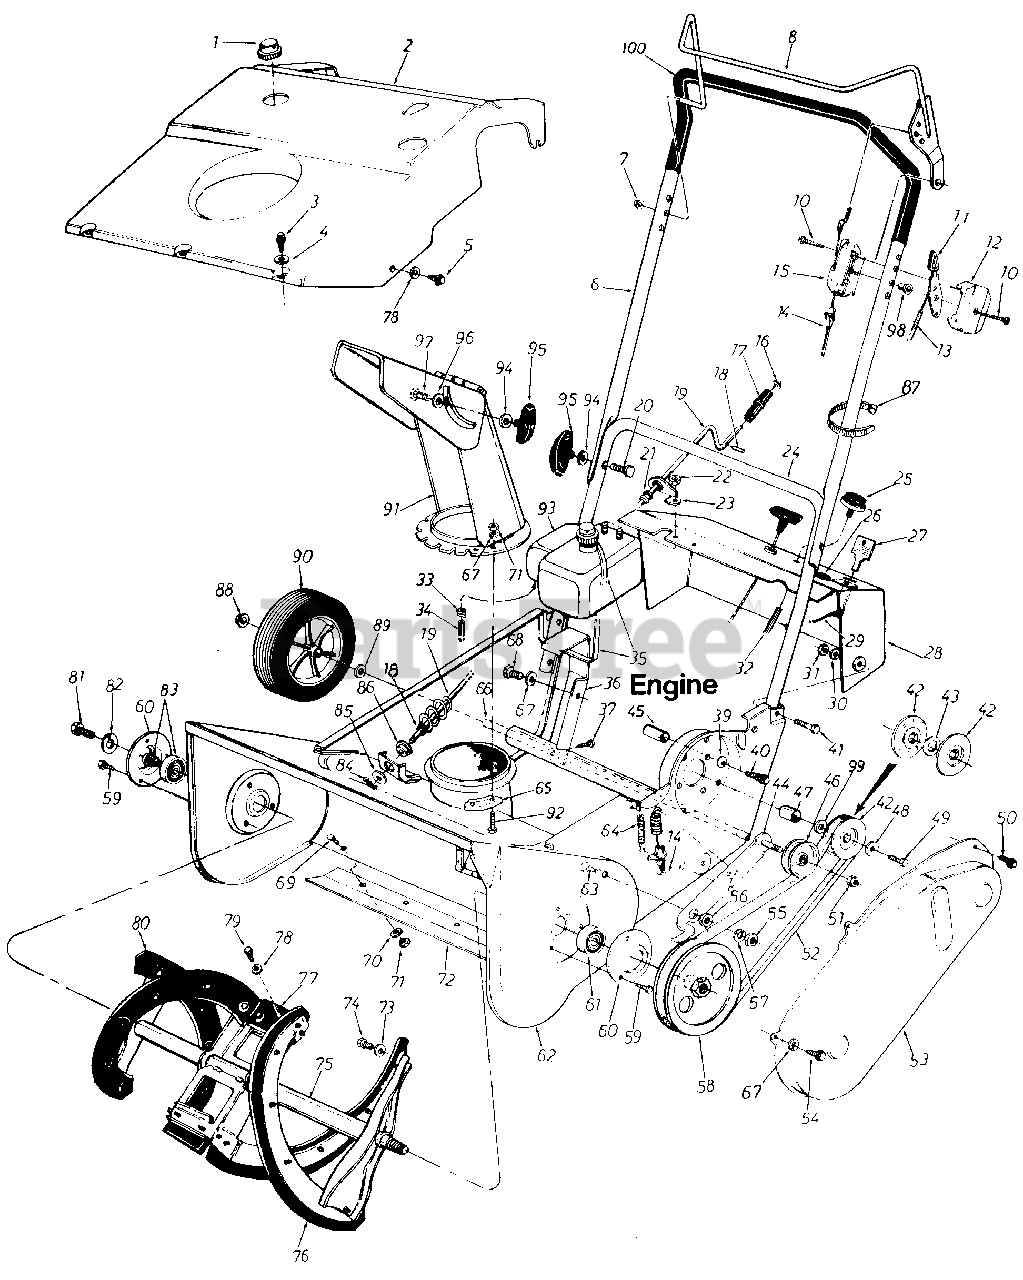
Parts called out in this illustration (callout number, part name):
1	Gas Tank Cap
2	21" Shroud
3	Hex B-Tap Scr. #10 x .38" Lg.
4	Spr.-Wash. .206" I.D. x .448" O.D.
5	Hex L-Wash. Hd. AB-Tap 1/4 x .62" Lg.
6	Upper Handle
7	Cap Speed Nut
8	Control Handle Ass'y. L.H.
10	Truss Mach. Hi-B Tap Scr. #12 x 1.5" Lg.
11	Throttle Lever
12	Control Panel Half
13	Throttle Wire 35"
14	Clutch Cable 35" Lg.
15	Clutch Panel Half
16	Push Cap 3/8" Rod
17	Knob 3/8" Dia. Hole
18	Roll Pin 1/8" Dia. x .63" Lg.
19	Chute Crank Ass'y.
20	Curved Carriage Bolt 5/16-18 x 1.75" Lg.
21	Chute Crank Grommet
22	Hex L-Nut 1/4-20 Thd.
23	Upper Chute Crank Brkt.
24	Lower Handle
25	Primer
26	Plastic Plug
27	Plastic Key
28	Dash Panel Ass'y.
29	Ignition Wire
30	L-Wash. 5/16" I.D.
31	Hex Nut 5/16-18 Thd.
32	Primer Hose 11" Lg.
33	Hose Clamp .406" Dia.
34	Gas Line 9" Lg.
35	Cable Tie 17.75" Lg.
36	Engine Support Brkt.
37	Hex L-Wash. Hd. AB-Tap Scr. 1/4 x.62" Lg.
39	Bell-Wash. .345" I.D. x .88" O.D.
40	Hex Bolt 5/16-18 x 1.5" Lg.
41	Hex Bolt 5/16-18 x 1.5" Lg.
42	3/8" "V"-Pulley Half .625" I.D. x 6.0 " O.D.
43	Fl.-Wash. .635" I.D. x .93" O.D.
44	Idler Brake Brkt. Ass'y.
45	Spacer .325" I.D. x .625" O.D. x .875"
46	Fl-Idler w/Flanges 2.12" O.D.
47	Spacer .635" I.D. x .89" O.D. x .57"
48	Bell-Wash. .345" I.D. x .88" O.D.
49	Hex Bolt 5/16-24 x .75" Lg.
50	Hex L-Wash. Hd. AB-Tap Scr. 1/4 x .62" Lg.
51	Hex Patch L-Nut 3/8-24 Thd.
52	"V"-Belt
54	Hex B-Tap Scr. 1/4" x .38" Lg.
55	Hex Nut 5/16-18 Thd.
56	Shld Spacer .50" Dia. x .27" Lg.
57	L-Wash. 5/16" I.D.
58	1/2" "V"-Pulley 1/2-20 LH. x 6" O.D.
59	Hex B-Tap Scr. 1/4" x .38" Lg.
62	21" Blower Hsg. Ass'y.
63	Truss Mach. Scr. 5/16-18 x .75" Lg.
64	Extension Spring .33" O.D. x 1.12" Lg.
65	Chute Flange Keeper
66	Wheel Axle Tubing
67	L-Wash. 1/4" I.D.
68	Hex Wash. S-Tap Scr. 1/4-20 x.50" Lg.
69	Carriage Bolt 1/4-20 x .62" Lg.
70	Fl.-Wash. .281" I.D. x .73 0. D.
71	Hex Nut 1/4-20 Thd.
72	Shave Plate
73	Fl-Wash. .281" I.D. x .50" O.D.
74	Hex Wash. B-Tap Scr. 1/4 x .62"
75	Auger Ass'y. 21
76	Rubber Spiral L.H.
77	Rubber Paddle
78	Fl-Wash. .218" I.D. x .62" O. D
79	Hex Wash. B-Tap Scr. #10 x .62" Lg.
80	Rubber Spiral R.H.
81	Hex Wash. TT-Tap Cl-Scr. 1/4-20 x .75" Lg.
82	L-Wash. 1/4" I.D.
83	Kit Bearing and Collar
84	Cotter Pin 3/32" Dia. x .75"
85	Fl-Wash. .390" I.D. x 1.50" 0. D.
86	Hex Bushing .385" I.D.
87	Cable Tie
88	Push Cap 1/2" Dia.
89	Fl-Wash. .510" I.D. x .75" O.D.
90	Wheel & Tire Ass'y. 6 x 1.5
91	5" Dia. Chute Ass'y.
92	Carriage Bolt 1/4-20 x .75" Lg
93	Fuel Tank Two Qt.
94	Bell-Wash. .345" I.D. x .88" 0. D.
95	Knob Handle Ass'y.
96	Fl-Wash. .328" I.D. x .68" O.D.
97	Carriage Bolt 5/16-18 x .62" Lg.
98	Control Disc Pin
99	Fl.-Wash .635 I.D. x 1.04 O.D
